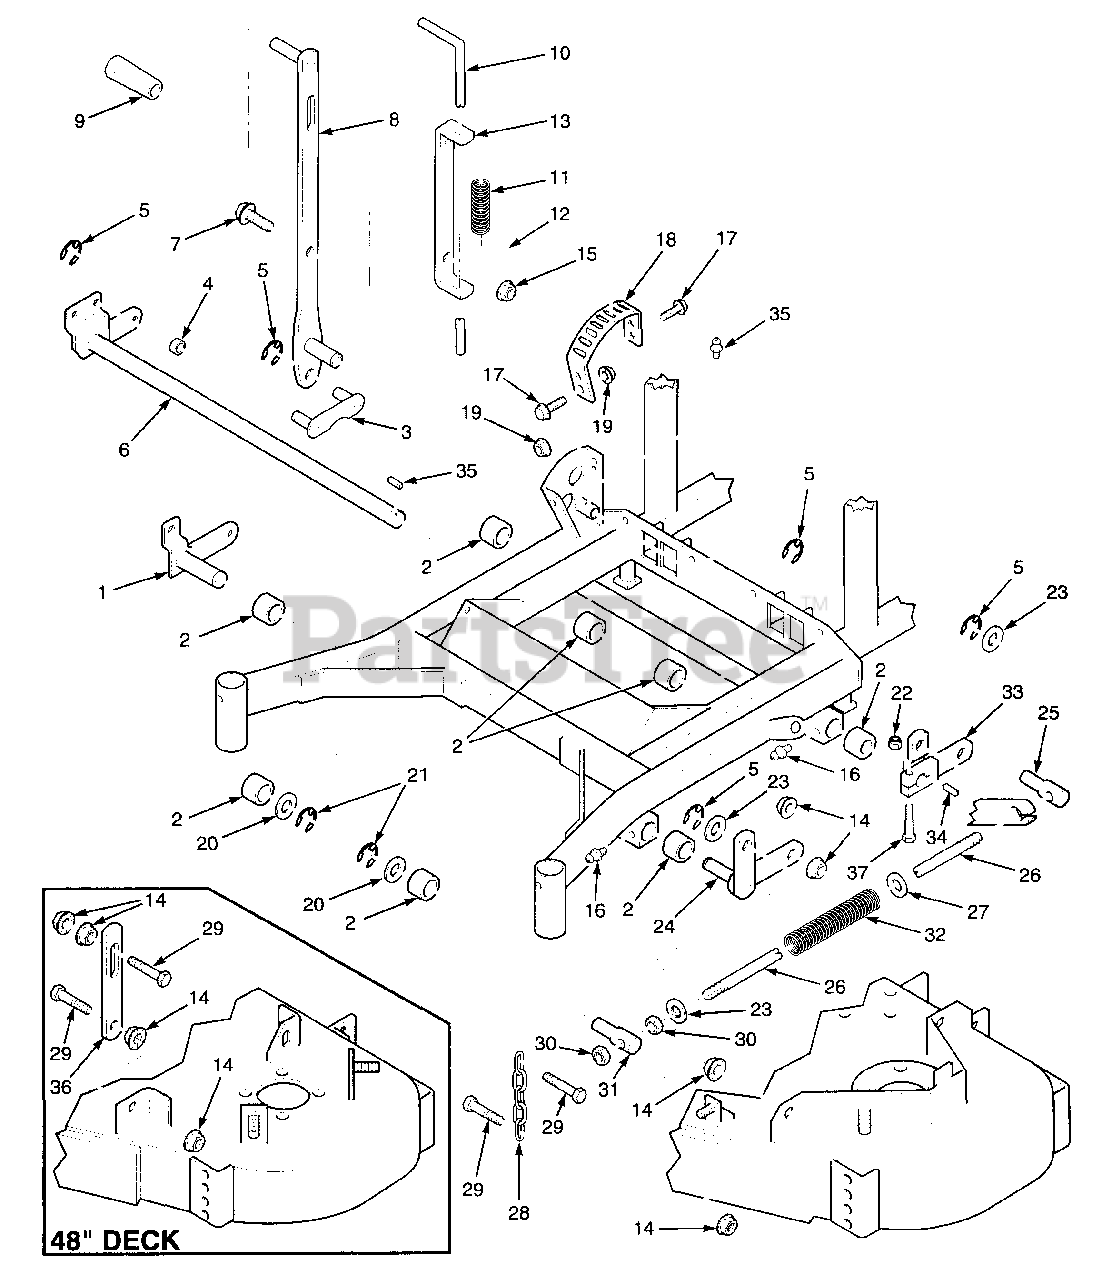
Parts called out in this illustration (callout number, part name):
1	Bellcrank, Lift - Right Front
2	Bushing
3	Lift Link
4	Bushing
5	Retaining Ring, 5/8" External "E"
6	Lift Arm Weldment
7	Bolt, Serrated Flange Hex Head 5/16-18 x 1"
8	Height Adjustment Lever
9	Grip, Lever Lift
10	Rod, Cutter Deck Lock
11	Spring, Deck Lift Index
12	Roll Pin, 5/32 x 3/4"
13	Lock, Rod Guide
14	Nut, Serrated Flange Hex 3/8-16
15	Nut, Serrated Flange Hex 5/16-18
16	Grease Fitting
17	Bolt, Serrated Flange Hex Head 1/4-20 x 3/4"
18	Strip, Height Adjustment
19	Nut, Serrated Flange Hex 1/4-20
20	Flatwasher, 3/4" (.766 x 1.250 x .075)
21	Ring, Retaining 3/4" External "E"
22	Nut, Elastic Stop 3/8-16
23	Flatwasher, 5/8" (.656 x 1.312 x .075)
24	Bellcrank, Lift - Left Front
25	Swivel Joint - LH THD
26	Adjustment Stud
27	Flatwasher, 5/8" (.688 x 1.75 x .134)
28	Chain
29	Bolt, Hex Head 3/8-16 x 1-1/2"
30	Nut, Hex 5/8-11
31	Swivel Joint - RH
32	Spring, Deck Lift
33	Bellcrank
34	Key, 3/16 x 3/16 x .75"
35	Grease Fitting
36	Link, Deck Support
37	Bolt, Hex Head 3/8-16 x 2"
